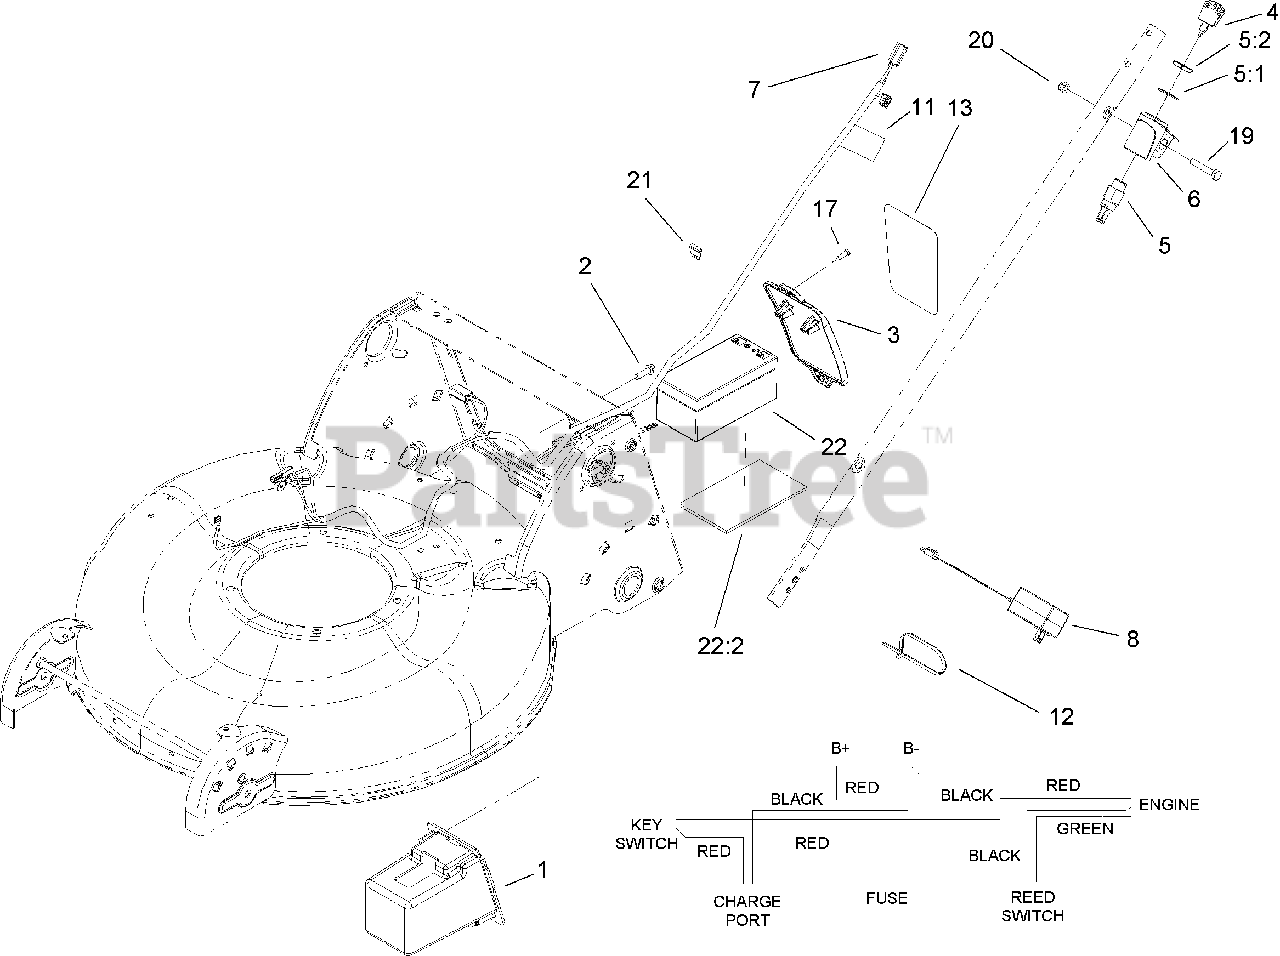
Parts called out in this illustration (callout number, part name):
1	BOX-BATTERY
2	SCREW-HWH
3	COVER-BATTERY
5	SWITCH-STARTER
5:1	WASHER-TOOTH
6	MOUNT-SWITCH
7	HARNESS-WIRE
8	CHARGER-12 VOLT
11	DECAL-HARNESS
12	STRAP-TIE
13	DECAL-INSTRUCTION, BATTERY
17	SCREW-PPH
19	SCREW-HH
20	NUT-LOCK, NI
21	FUSE-40 AMP
22:2	FOAM-BATTERY
